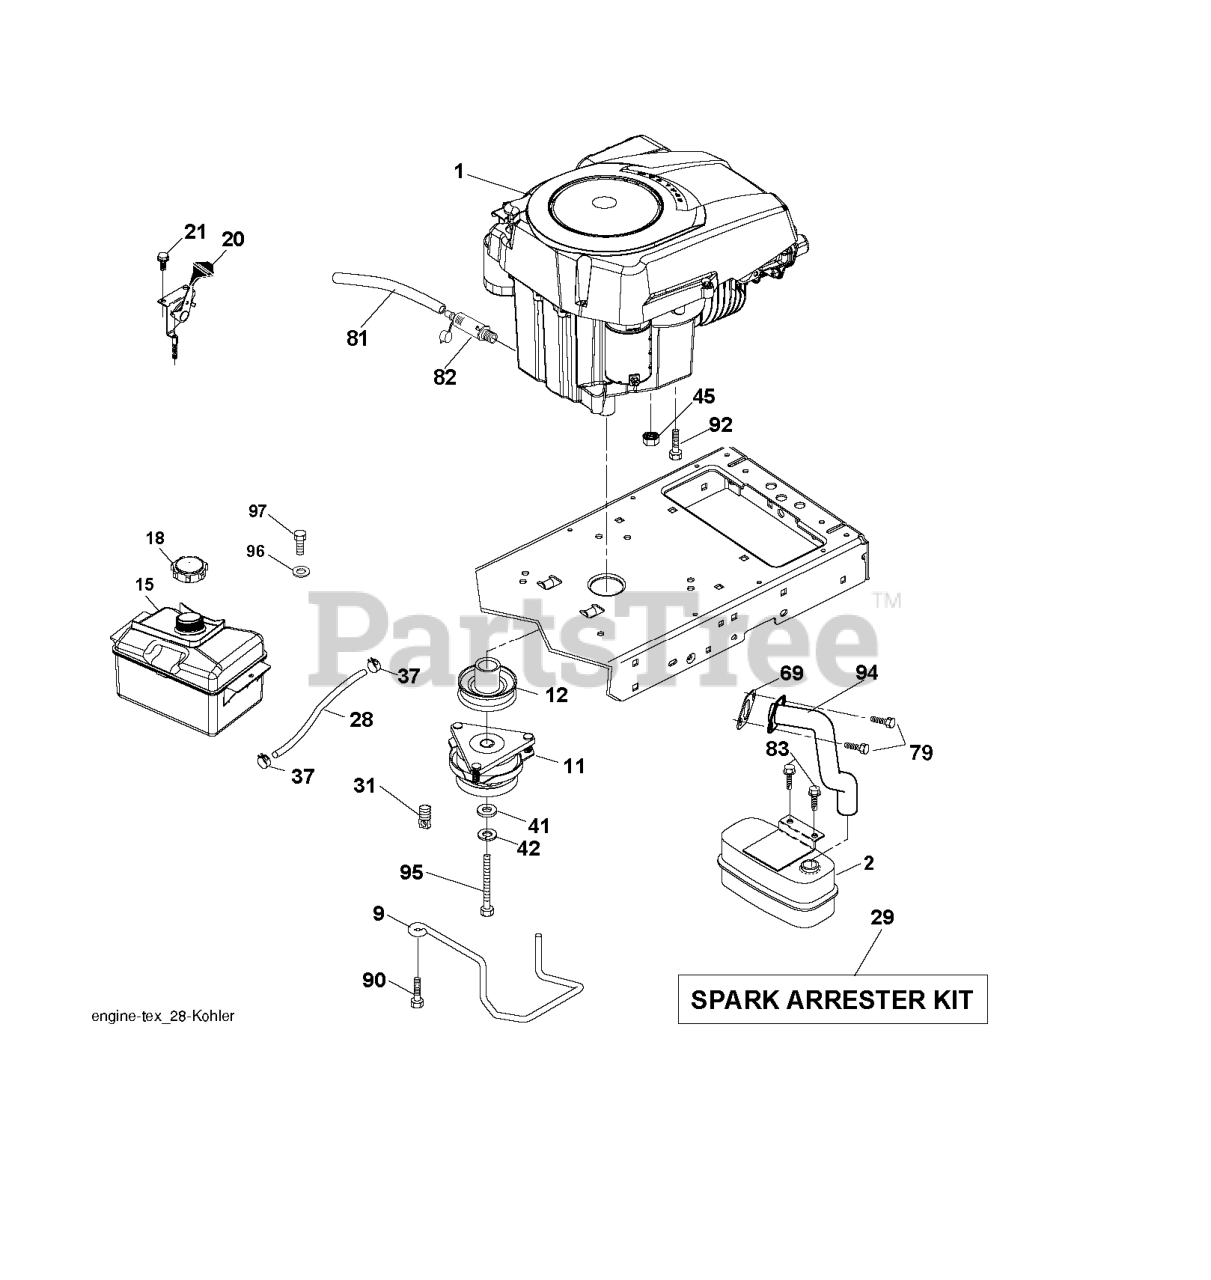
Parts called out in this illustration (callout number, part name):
2	MUFFLER.SINGLE.CYL.KOHL/B&S
9	KEEPER.BELT.ENGINE.4.2
11	RB.CLUTCH.OGURA.4.4.PD
12	PULLEY.ENGINE.TUFFTORQ
15	RP TANK FUEL FRT 1.5 GAL
18	FUEL CAP
20	CONTROL.TH/CK.C.
21	SCREW
28	LINE.FUEL.20
29	KIT.SPARK ARRESTOR 794945 B&S
37	HOSE CLAMP
42	LOCKWASHER
45	NUT
79	SCREW.SOCKET HD.5/16-1
81	TUBE, DRAIN OIL ASM.
82	PLUG DRAIN OIL EASY
83	BOLT.5/16-18UNCX3/4 W/SEMS.BLK
90	SCREW 3/8-16X1
92	SCREW 3/8-16X1
94	RP.TUBE.EXHAUST.KOHL.COURAGE
95	BOLT HEX 7/16-20X4-1/4"
97	SCREW HEXWSHR 1/4-20X3/4
